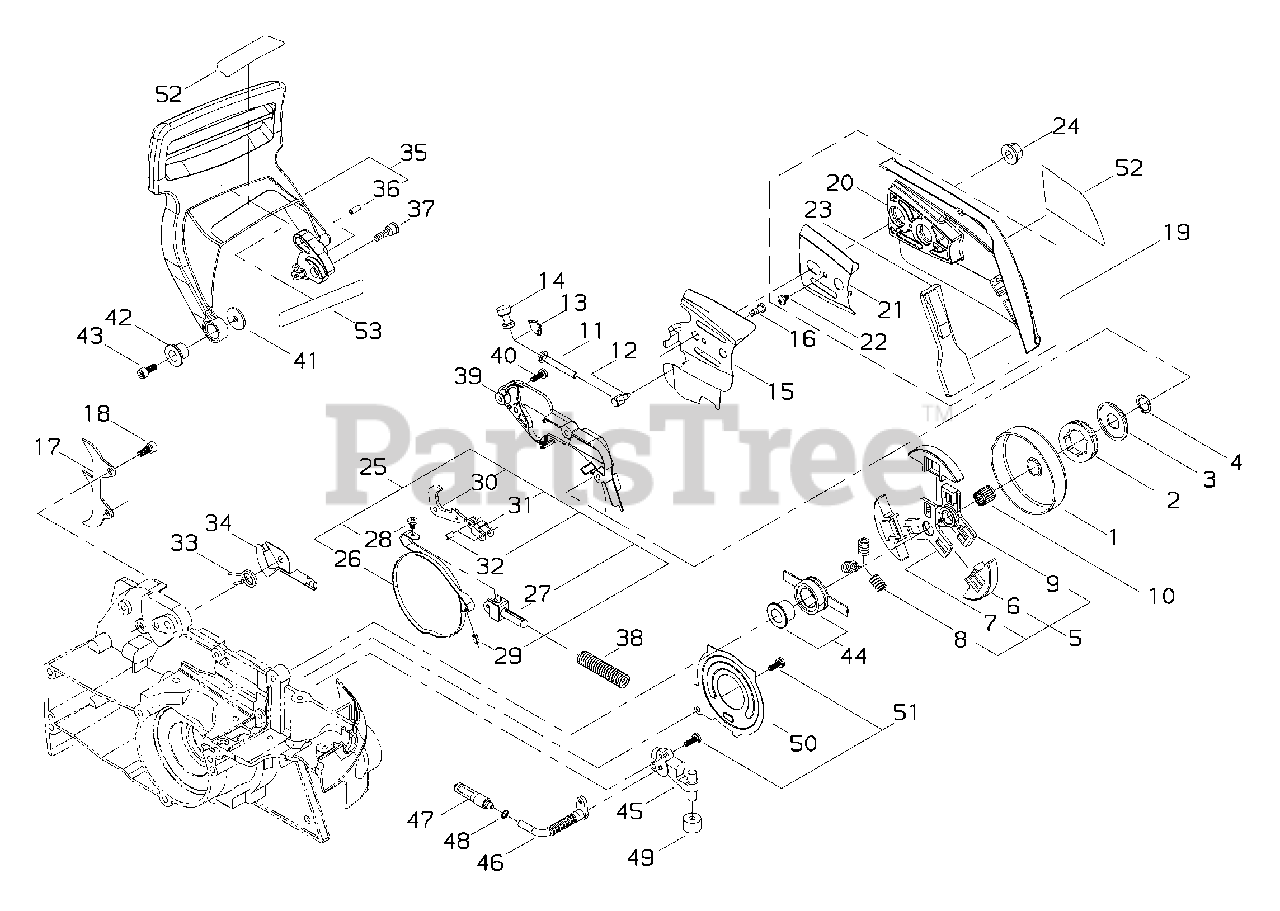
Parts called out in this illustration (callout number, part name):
1	DRUM, CLUTCH
2	SPROCKET, RIM
3	COLLAR
4	RING, RETAINING - 10
5	CLUTCH ASSY
6	SHOE, CLUTCH
7	HUB, CLUTCH - INNER
8	SPRING, CLUTCH
9	HUB, CLUTCH - OUTER
10	BEARING, NEEDLE
11	SCREW
12	TENSIONER, CHAIN
13	GUIDE
14	GEAR, TENSIONER
15	PLATE, GUIDE - INNER
16	SCREW - 4X7
17	SPIKE
18	SCREW - 5X12
19	CLUTCH COVER ASSY
20	COVER, CLUTCH
21	PLATE, GUIDE
22	SCREW - 4X6 -- TAPPING
23	PROTECTOR
24	NUT, GUIDE BAR
25	BRAKE BAND ASSY
26	BAND, BRAKE
27	HOLDER, BRAKE SPRING
28	SCREW - 4X10 -- TAPPING
29	PIN - SPRING -- 4X8
30	LEVER, BRAKE
31	TIE, CABLE
32	TIE, CABLE - 3X11.8
33	SPRING
34	PLATE
35	BRAKE LEVER KIT
36	PIN - LOCATING
37	BOLT
38	SPRING, BRAKE
39	COVER, BRAKE
40	SCREW - 4X14
41	WASHER
42	COLLAR
43	SCREW - 5X12
44	GEAR ASSY
45	AUTO-OILER ASSY
46	PIPE - OIL
47	FILTER, OIL
48	RING, RETAINING - 6
49	FILTER, OIL
50	COVER, PUMP
51	SCREW - 4X14
52	LABEL - MODEL 446s
53	LABEL - CAUTION
